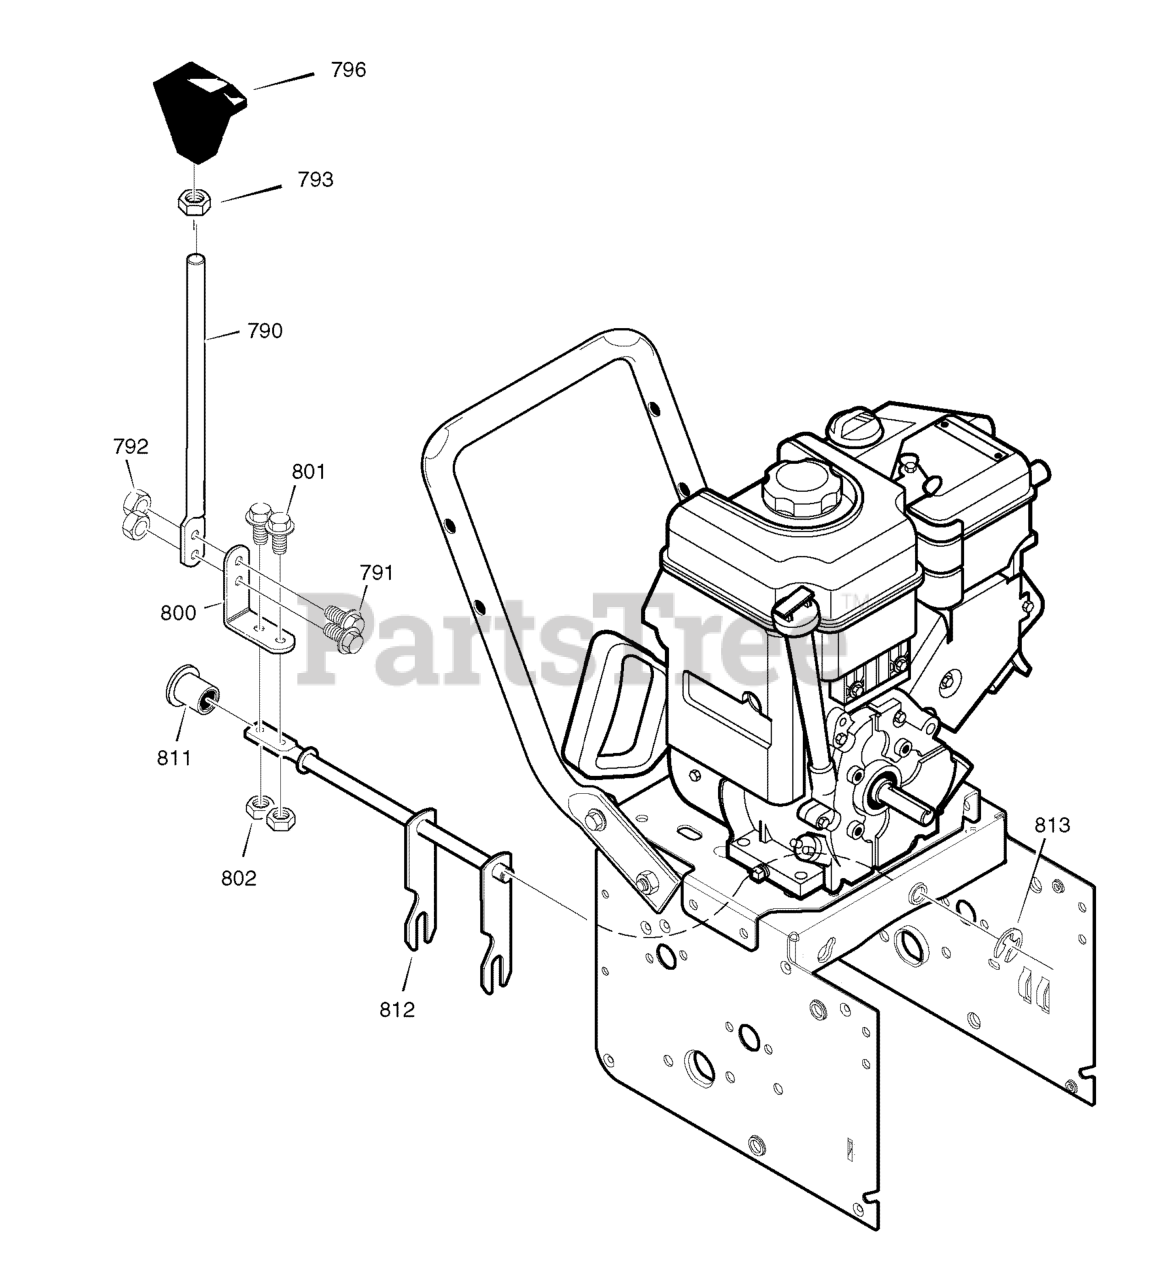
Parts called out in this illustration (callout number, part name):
790	ROD, Shift
791	SCREW, 1/4 - 20 x 3/4
792	NUT, 1/4 - 20
793	NUT, Jam
796	KNOB
800	LEVER, Spring
801	SCREW, 1/4 - 20 x 3/4
802	NUT, 1/4 - 20
811	BEARING, Flange
812	ROD ASSEMBLY, Speed Select
813	RETAINER, Ring
